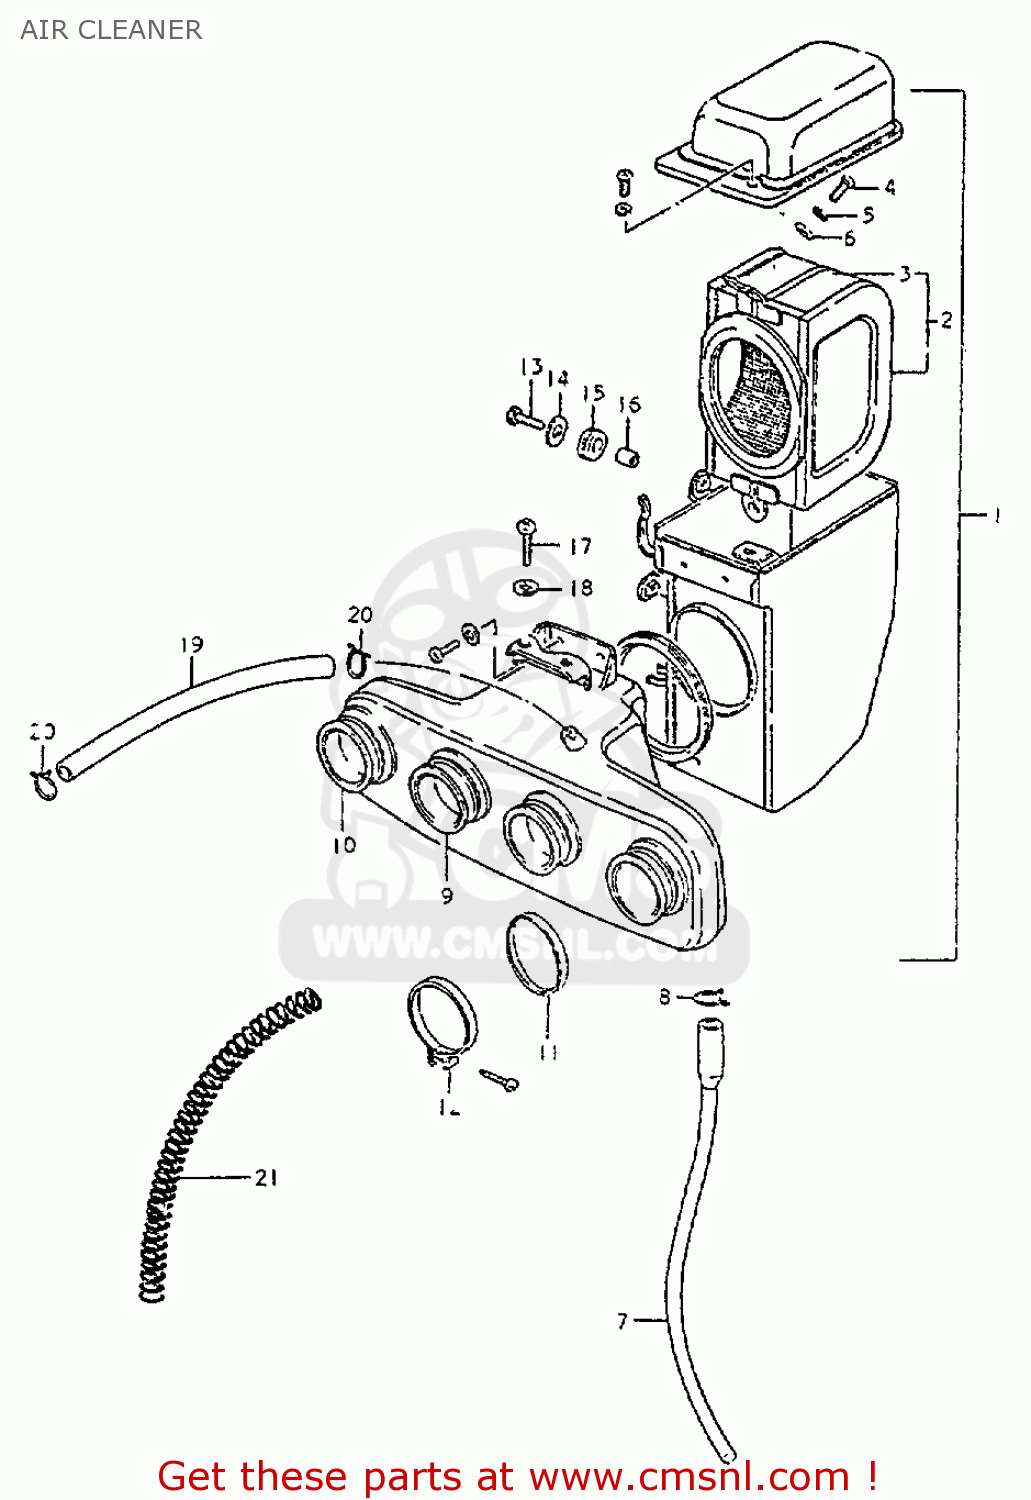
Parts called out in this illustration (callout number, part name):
1	CLEANER ASSEMBLY,AIR
2	FILTER ASSY
3	FILTER
4	SCREW
5	LOCK WASHER
6	WASHER
7	DRAIN TUBE
8	CLIP
9	TUBE,AIR CLEANER OUTLET A
10	TUBE,AIR CLEANER OUTLET B
11	RING,CARBURETOR AIR INLET HOSE
12	CLAMP
13	BOLT
14	WASHER
15	CUSHION
16	SPACER (6.1X9X9)
17	SCREW 6X12
18	WASHER
19	HOSE
20	CLIP
21	SPRING
